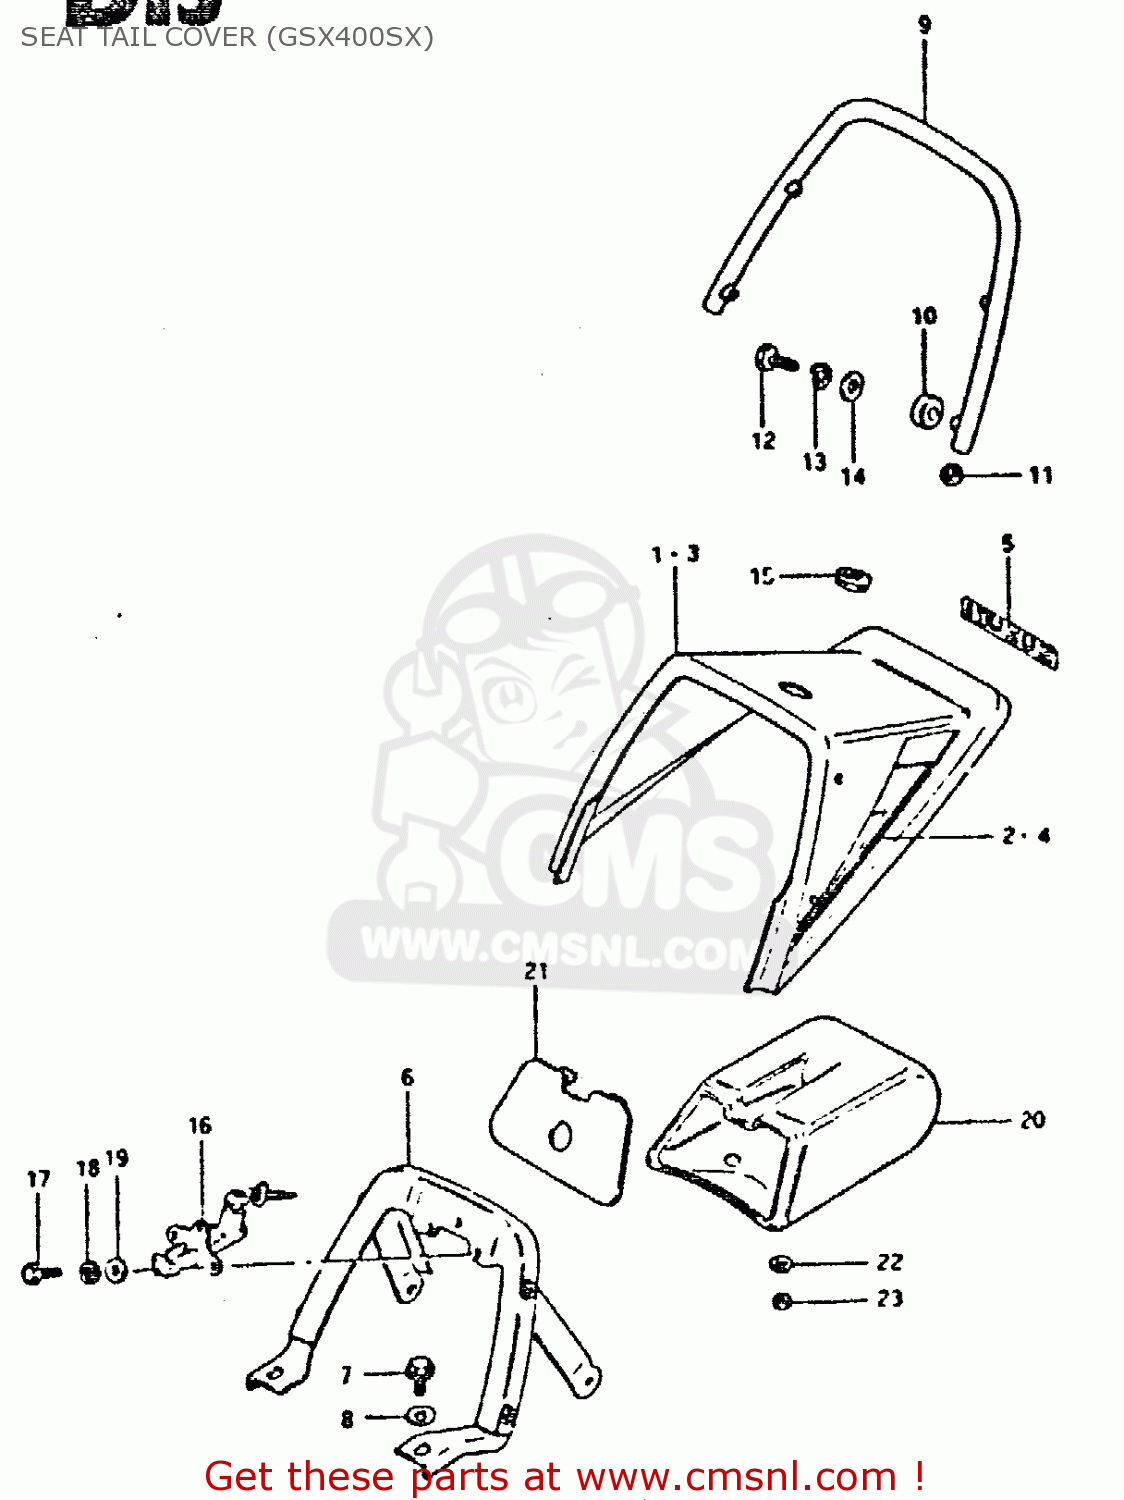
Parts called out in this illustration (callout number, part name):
1	COVER,SEAT TAIL
2	TAPE SET
3	TAIL COVER, SEAT (WHITE)
4	TAPE SET
5	EMBLEM,SEAT TAIL COVER
6	BRACKET, SEAT TAIL COVER
7	BOLT
8	WASHER (8.7X22X2)
9	HANDLE,PILLION RIDER
10	CUSHION
11	END,SHEET HANDLE
12	BOLT (8X30)
13	LOCK WASHER
14	WASHER
15	GROMMET,SEAT LOCK HOLE
16	LOCK SET,SEAT
17	BOLT
18	LOCK WASHER
19	WASHER
20	BOX, SEAT TAIL
21	LID,SEAT TAIL BOX
22	WASHER
23	NUT 6MM
